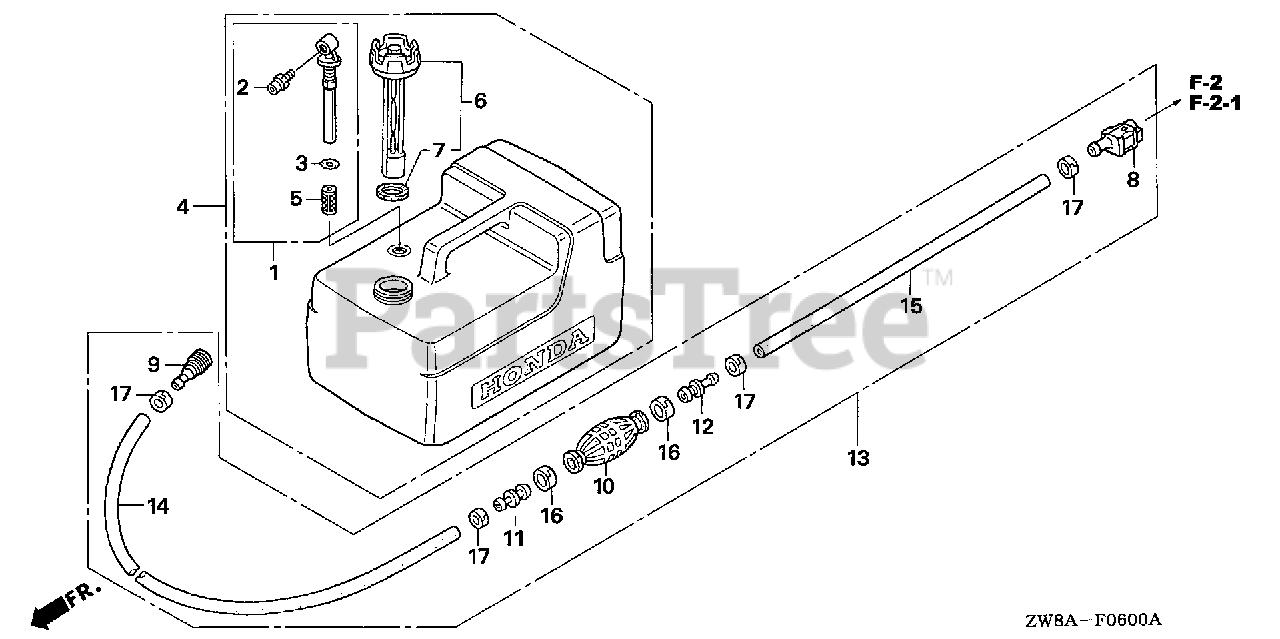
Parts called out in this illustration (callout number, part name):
1	JOINT ASSY., FUEL
2	FITTING, QUICK DISCONNECT
4	TANK ASSY., FUEL
5	FILTER, FUEL
6	CAP, FUEL FILLER
7	GASKET, FUEL CAP
8	CONNECTOR ASSY., FUEL (A)
9	CONNECTOR, FUEL
10	BULB, PRIMER
11	VALVE, IN.
12	VALVE, OUTLET
13	TUBE ASSY., FUEL
14	TUBE, FUEL LONG (7.3X2000)
15	TUBE, FUEL SHORT (6.3X500)
16	BAND, TUBE CLIP (20MM)
17	BAND, TUBE CLIP (12.5MM)
